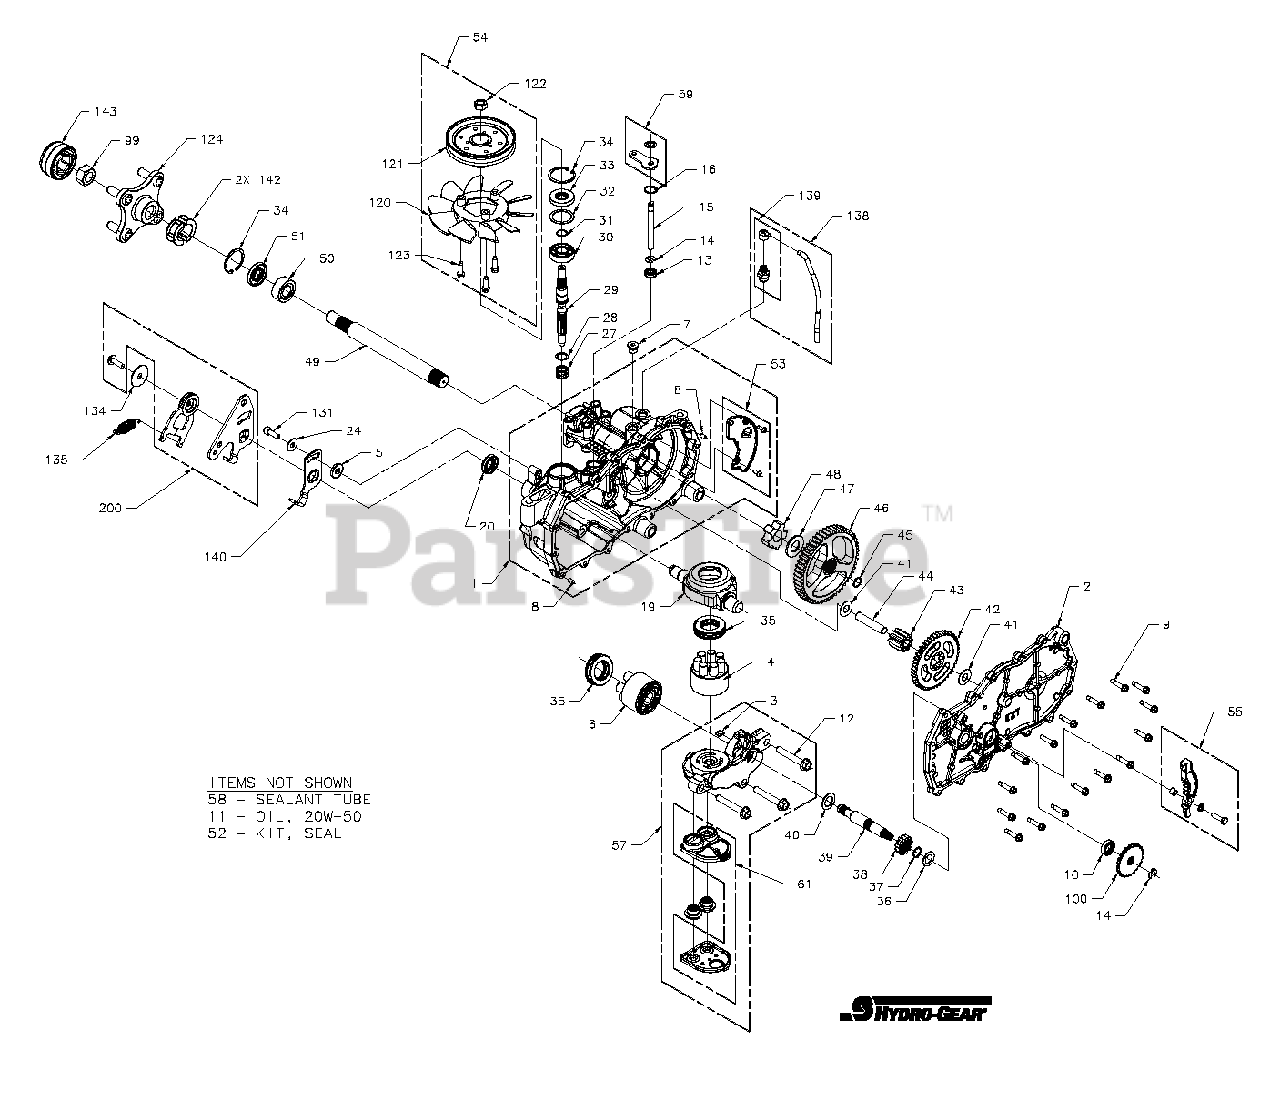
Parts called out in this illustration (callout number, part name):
4	ASSEMBLY, PUMP BLOCK (7P-10CC)
6	ASSEMBLY, MOTOR BLOCK (5P-10CC)
10	KIT, BRAKE SEAL
13	SEAL, LIP .375 X .75 X .25
14	RING, RETAINING .375 EXT
19	SWASHPLATE, TRUNNION, MACHINED
20	SEAL, LIP 18 X 32 X 7
28	WASHER .591 X .787 X .040
29	SHAFT, INPUT
30	BEARING, BALL 17MM ID X 40 MM OD X 12 MM
33	SEAL, LIP 17 X 40 X 7
34	RING, RETAINING
35	BEARING, THRUST 20 X 52 X 13
41	WASHER, HT .5 ID X 1.0 OD X .032
45	RING, SPIRAL RETAINING
50	BUSHING, AXLE
51	SEAL LIP .75 X 1.5
52	KIT SEAL
55	KIT BRAKE ARM
58	SEALANT TUBE, 10.3oz
99	NUT, HEX 3/4-16
100	DISC, COG BRAKE
121	PULLEY 4/5 X 1.625
124	KIT, HUB 1/2-20
134	WASHER 1.5 X .34 X .062
135	SPRING EXTENSION
